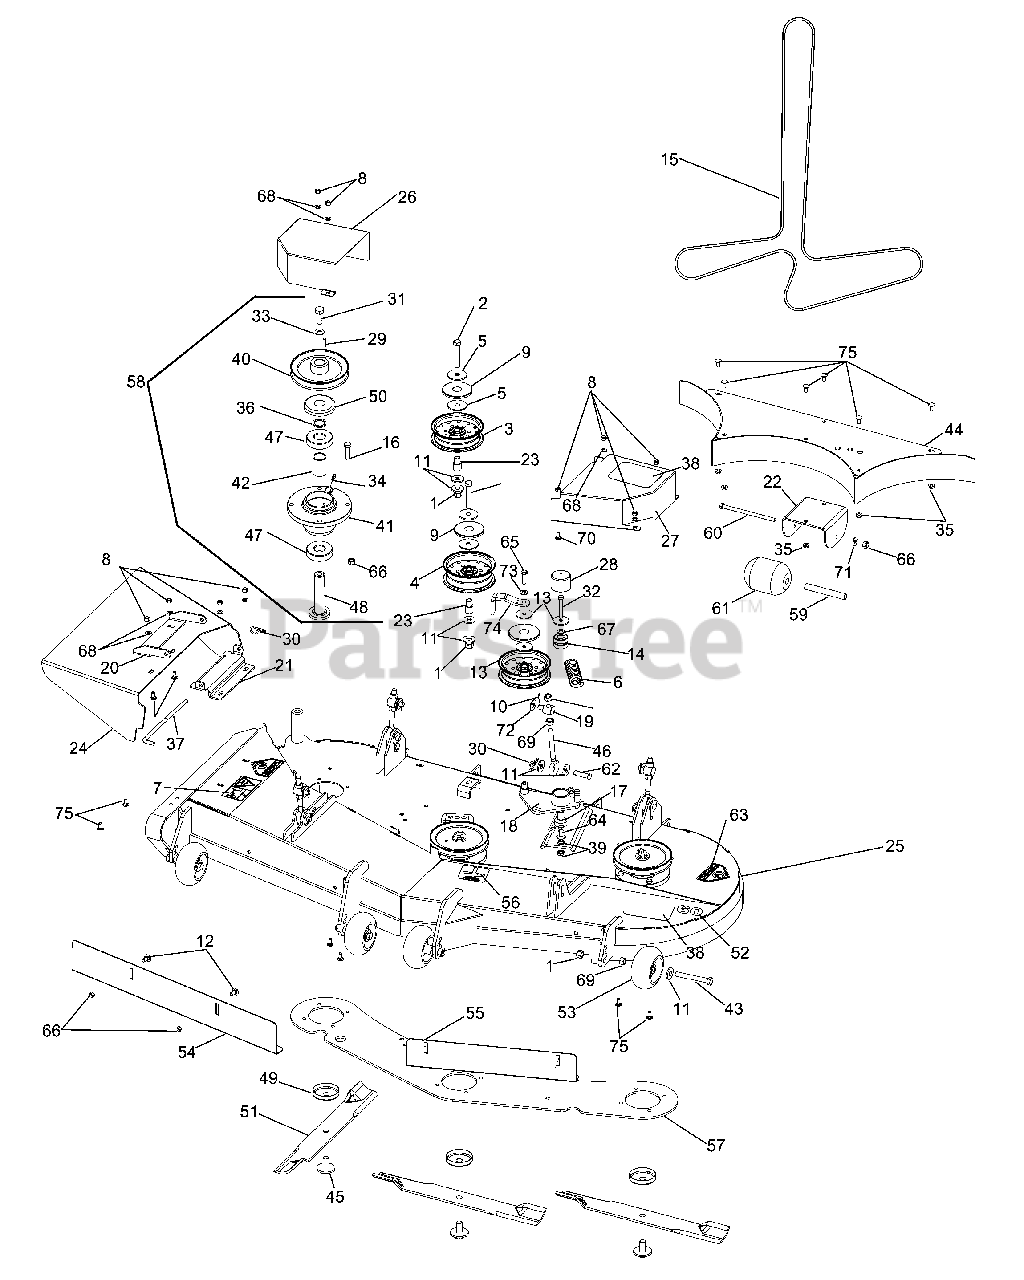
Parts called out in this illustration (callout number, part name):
1	NUT 1/2-13 HEX NYLOC ZD
2	SCREW, 1/2C X 3 HEX CAP
3	IDLER PULLEY
4	IDLER PULLEY (TALL)
5	ISOLATOR WASHER
6	DECK SPRING
7	DECAL, EURO SEVERING
8	NUT 5/16 NYLOC
9	TOP DUST CAP
10	PIN COTTER 1/8 X 1 ZD
11	WASH USS FLAT 1/2
12	RHSNB 3/8-16 X 3/4 GR5 ZD
13	WASHER, 3/8 SPEC
14	BEARING, BALL
15	BELT, DECK 52 COMBI/60 GRIZZY
16	HCS 3/8C X 1 1/2
17	BEARING PIVOT SPACER
18	ARM, IDLER - WELDMENT
20	HINGE, DISCHARGE CHUTE, BLUE
21	SUPT - CHUTE HINGE PAINTED
22	REAR CENTER ROLLER BKT 60 BLK
23	SPACER - IDLER
24	CHUTE - 60" PAINTED
25	DECK W/DECAL 60" GRIZZLY
26	PULLEY GUARD RH 60 PAINTED
27	PULLEY GUARD LH 60 PAINTED
28	CAP, VINYL
29	KEY - 1/4 X .88
30	PIN, COTTER 1 3/4
31	1/2-20 UNF X 1 1/4 HHBLT
32	HCS 3/8C X 2 1/2
33	WASHER .525 X 1.375 X .25
34	ZERK, 3/16, DRIVE IN
35	5/16-18 FLANGED L-NUT
36	SPACER .25
37	DEFLECTOR PIN
38	REAR FLOOR PAD-LH
39	NUT 3/8C WHIZ
40	PULLEY 6.45 METRIC
41	DECK HUB MACHINED
43	HCS 1/2-13 X 4 GR 5 ZD
44	W-BAFFLE WLDT.
45	BLADE BOLT/WASHER
46	BOLT, EYE
47	BEARING - 6305 - 2RS
48	SHAFT SHORT
49	TRASH GUARD
50	TRASH GUARD
51	BLD 60" HI LIFT FUSION
52	DECAL, DECK 60"
53	GUAGE WHEEL
54	BLOW BY BAFFLE
55	BLOW BY BAFFLE LH 60
56	DECAL, BELT ROUTING (18656)
57	HUB STIFFENER PLATE
58	SPINDLE ASSEMBLY
59	BUSHING
60	3/8-16 X 6-1/2 HHB GR8
61	ROLLER 3-3/4 DIA. X 4-1
62	CLEVIS PIN 1/2X1-3/4LG
63	DECAL, CPSC
64	HCS 3/8C X 1
65	HCS 3/8C X 1 1/4 GR5
66	NUT 3/8-16 NYLOC
67	WASHER 3/8 SAE FLAT
68	FLAT WASHER 5/16 SAE
69	NUT HEX 1/2
70	BOLT 5/16C X 3/4" CARRIAGE
71	WASHER 3/8 FLAT
72	WASHER 1/2 FLAT
73	SLW 3/8 STD
74	GUIDE, BELT
75	RHSSNB 5/16C X 1.0
